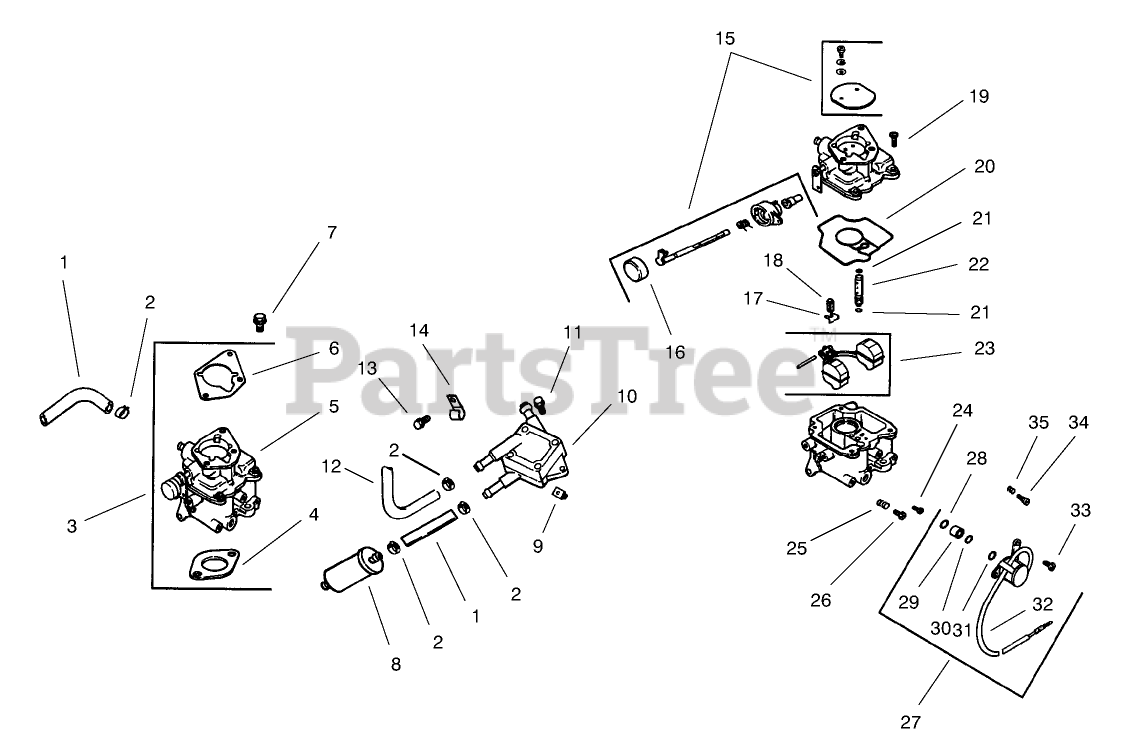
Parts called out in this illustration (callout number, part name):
1	Line-Fuel
2	Clamp
3	Kit, carburetor w/gasket (Includes 4-6)
4	Gasket-Air Cleaner
5	Carburetor assembly (Includes 15-35)
6	Gasket-Carburetor
7	Screw
8	Filter-Fuel
9	Nut
10	Pump-Fuel
11	Screw
12	Line, fuel17"
13	Screw
14	Clip-Cable (Only On: 72103)
15	Kit-Choke Repair (Incl. Ref. #33
16	Cap-Choke Lever Carburetor Assembly (Incl. Ref. #1-25 32)
17	Clip-Inlet Needle Valve
18	Valve-Inlet Needle
19	Screw
20	Gasket-Carburetor Body
21	ORing
22	Jet-Slow
23	Kit-Float Repair
24	Jet-Main
25	Spring-Idle Speed Adjust
26	Screw-Idle Speed Adjust
27	Kit-Solenoid Assembly
28	ORing
29	Seat-Solenoid
30	ORing
31	ORing
32	Solenoid
33	Screw
34	Needle-Idle Adjust
35	Spring-Idle Adjust
